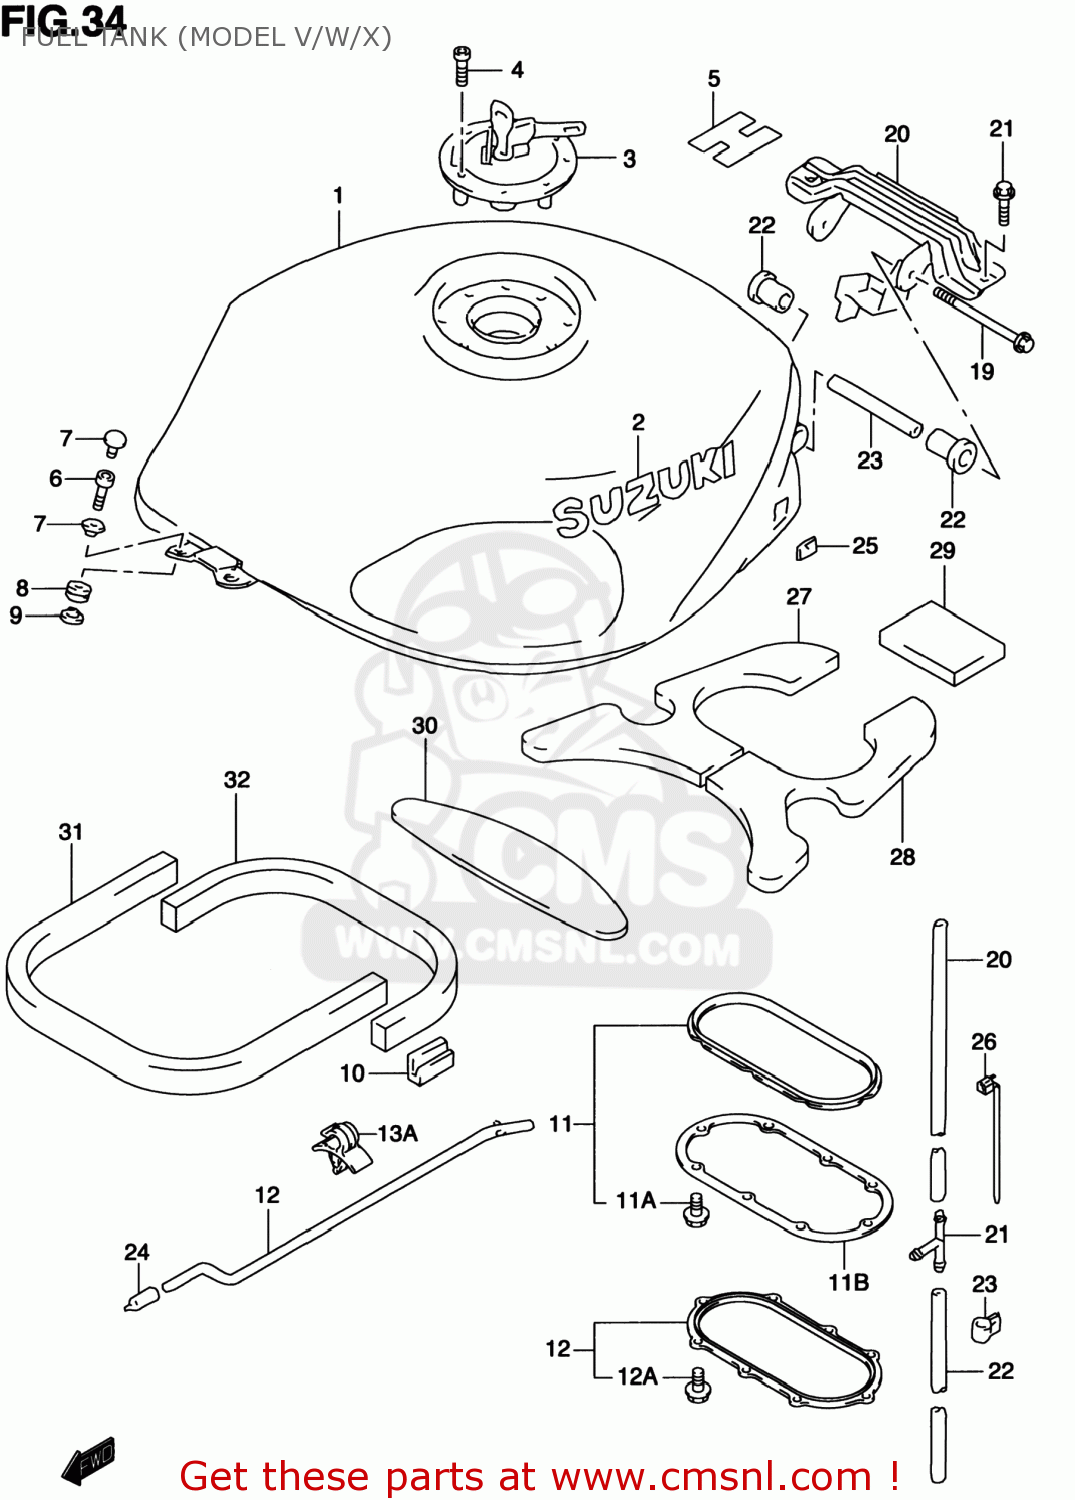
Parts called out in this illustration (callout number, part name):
1	TANK ASSEMBLY,FUEL
2	EMBLEM,FUEL TANK
3	CAP SET,FUEL TANK
4	BOLT(5X20)
5	BOLT
6	CAP,BOLT
7	WASHER(6.5X18X1.6)
8	CUSHION
9	WASHER
10	CUSHION,FUEL TANK SIDE
11	PACKING SET,FUEL PUMP (NAS)
11A	BOLT,FUEL PUMP
11B	PLATE,FUEL PUMP GASKET
12	PACKING SET,FUEL PUMP (NAS)
12A	BOLT,FUEL PUMP
13	STAY,FUEL TANK
13A	CLAMP
14	BRACKET,FUEL TANK,REAR
15	BOLT
16	CUSHION,FUEL TANK RR
17	FASTENER,FUEL TANK
18	SPACER,FUEL TANK RR
19	BOLT
20	HOSE,FUEL TANK DRAIN
21	3 WAY
22	HOSE(7X10.2X600)
23	CLAMP
24	CAP,OD:11
25	LABEL,FUEL TANK INNER
26	CLAMP(L:125)
27	SHIELD,FUEL TANK HEAT
28	SHIELD,FUEL TANK HEAT
29	SHIELD,FUEL TANK HEAT RR
30	SHIELD,FUEL TANK HEAT FR
31	SHIELD,FUEL TANK HEAT NO.1
32	SHIELD,FUEL TANK HEAT NO.2
